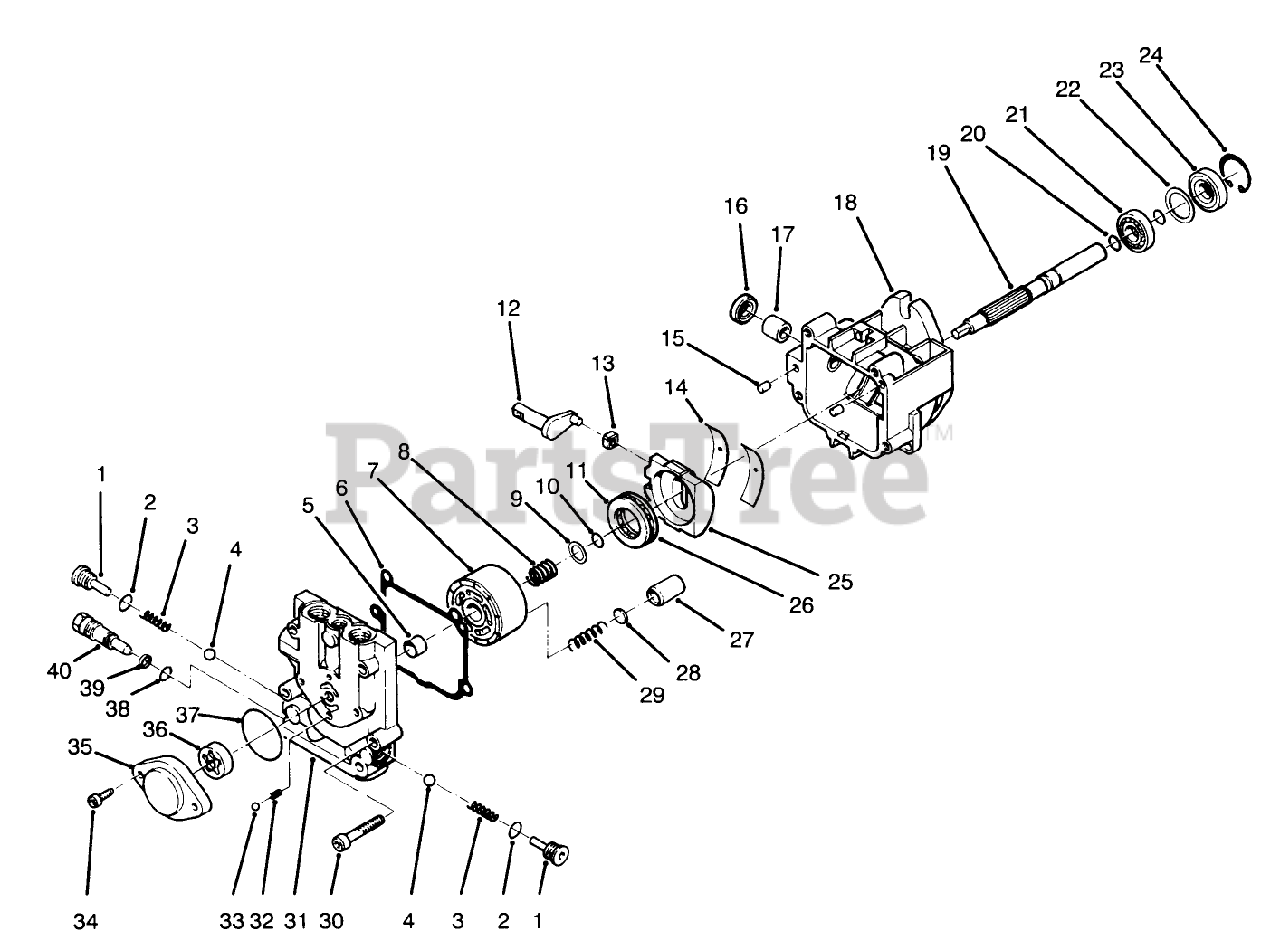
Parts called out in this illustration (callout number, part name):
1	Check Valve Kit (Incl. Ref. #2-4)
2	Seal-O-Ring
4	Ball
5	Journal-Bearing
6	Gasket-End Cap
9	Washer
11	Plate-Thrust
12	Arm-Trunion
13	Guide-Slot
14	Cradle-Bearing
16	Seal-Lip
17	Journal-Bearing
19	Shaft
21	Bearing-Ball
23	Seal-Lip
25	Swashplate Assembly
26	Roller-Thrust
29	Spring-Piston
32	Ball
35	Housing-Charge Pump
36	Gerotor Assembly
37	Seal-O-Ring
38	Seal-O-Ring
39	Ring-Back-Up
40	Valve-Bypass
